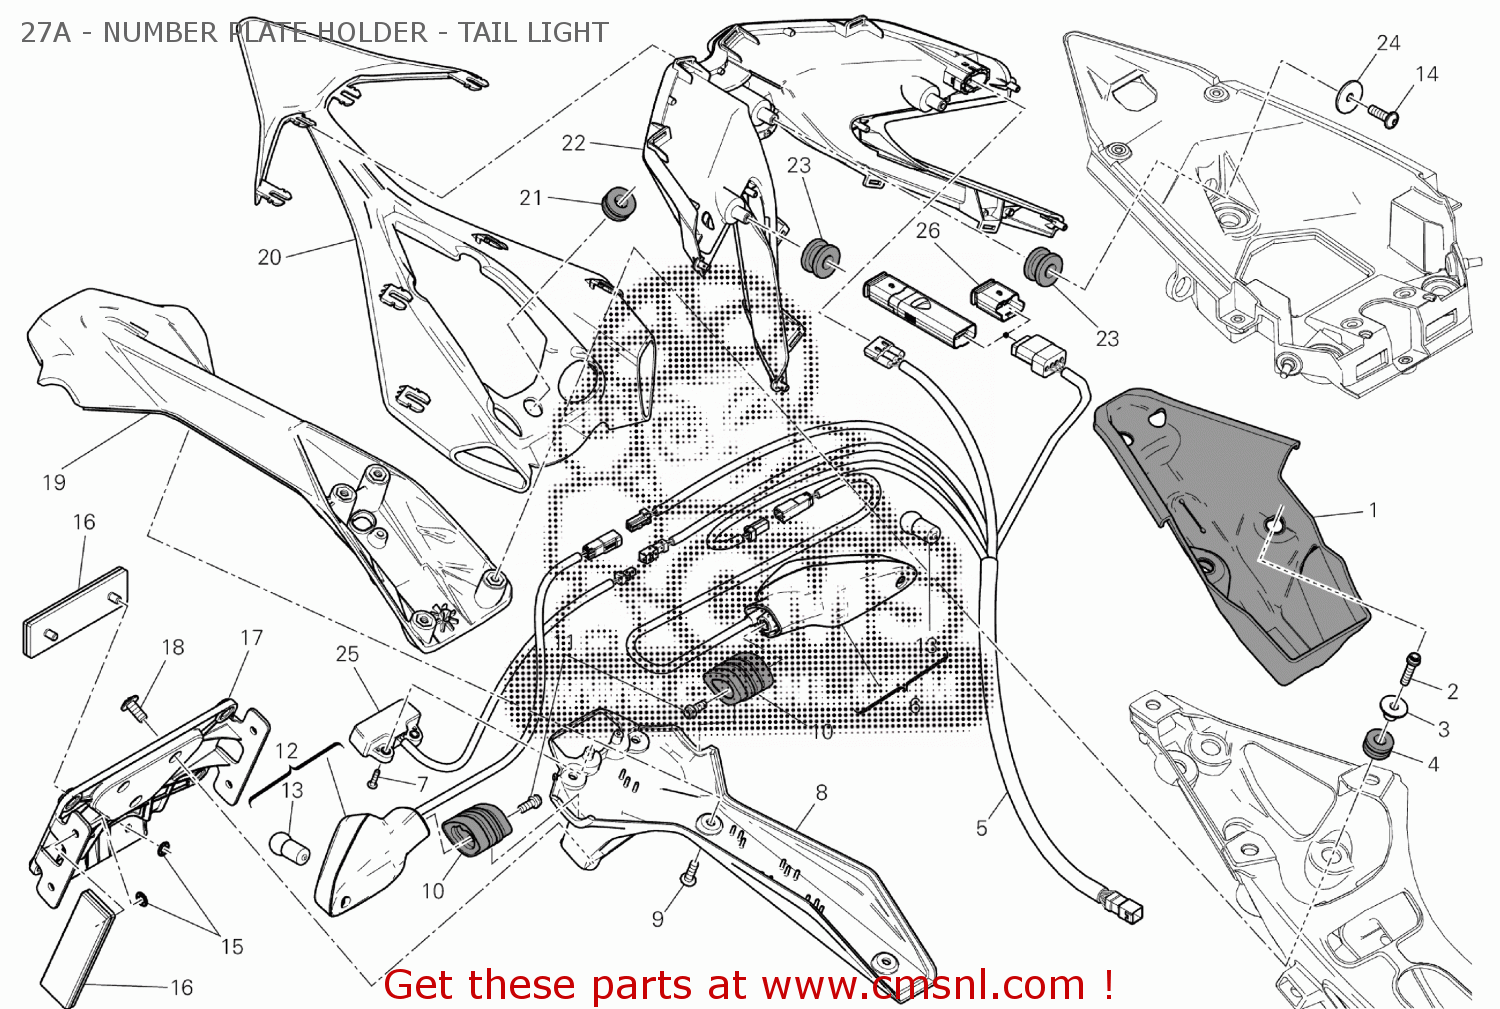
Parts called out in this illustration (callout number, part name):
1	RUBBER SECTION
2	SCREW
3	SPACER
4	VIBRATION DAMPER PAD
5	REAR WIRING
6	FLASHER LIGHT FRONT RH- REAR LH
7	SCREW
8	NUMBER PLATE HOLDER BOTTOM
9	SCREW
10	SPACER
11	SCREW TCEIF M5X12
12	FLASHER LIGHT FRONT LH - REAR RH
13	BULB
14	SCREW, TAPPING M4.5X12
15	CLIP
16	REFLEX REFLECTOR, REAR
17	NUMBER PLATE HOLDER
18	SCREW
19	NUMBER PLATE HOLDER UPPER
20	COVER, LOWER
21	RUBBER PAD
22	TAILLIGHT
23	RUBBER PAD
24	WASHER
25	LAMP, LICENSE PLATE
26	CAP DDA
